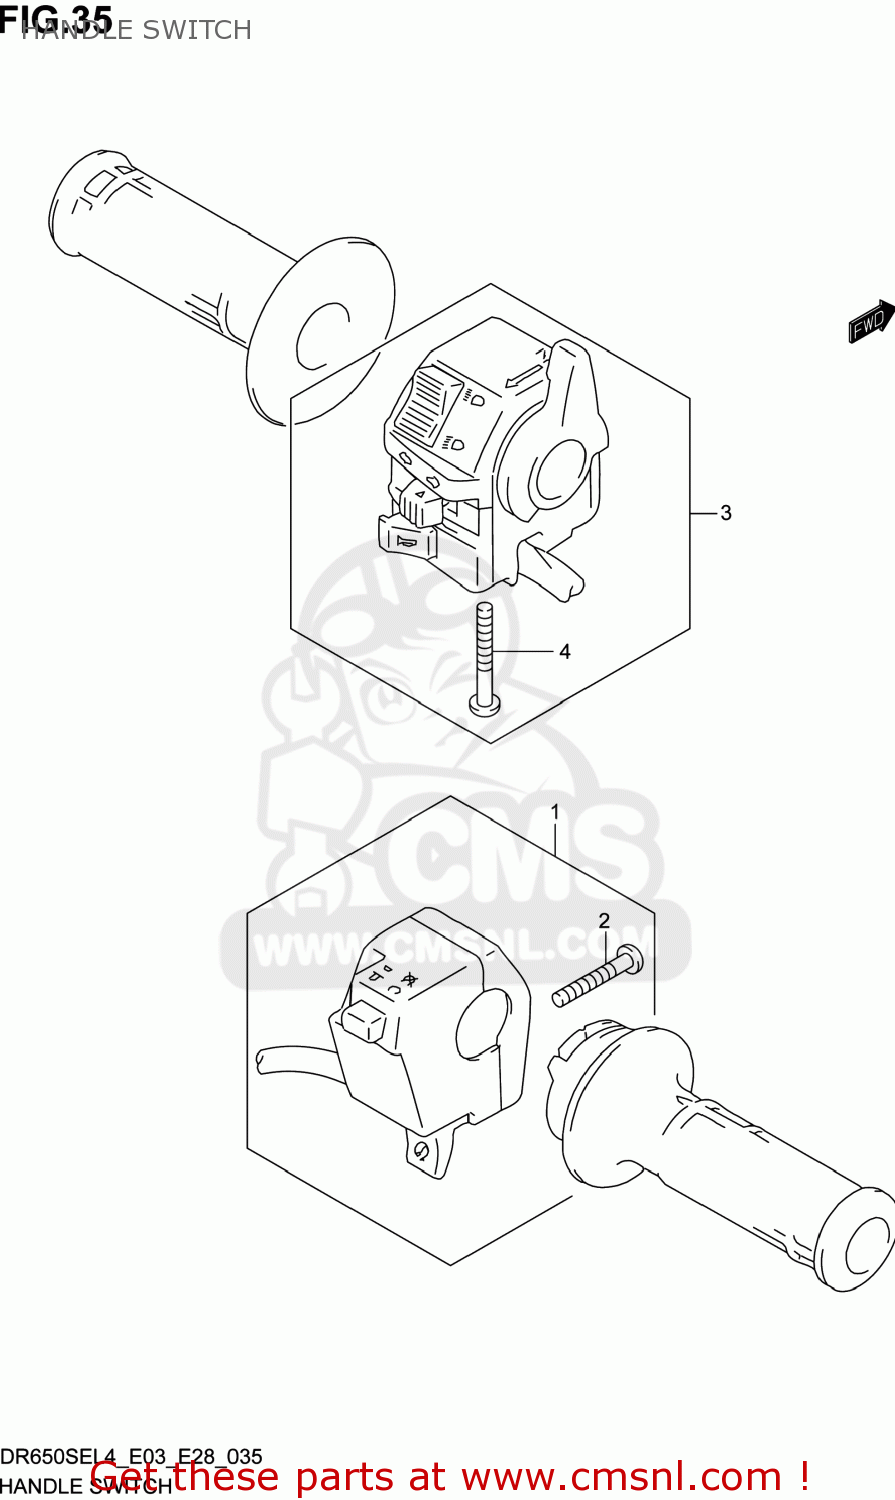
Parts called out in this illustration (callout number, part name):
1	SWITCH ASSY,HANDLE,R
2	SCREW(5X25)
3	SWITCH ASSY,HANDLE,L
4	SCREW
